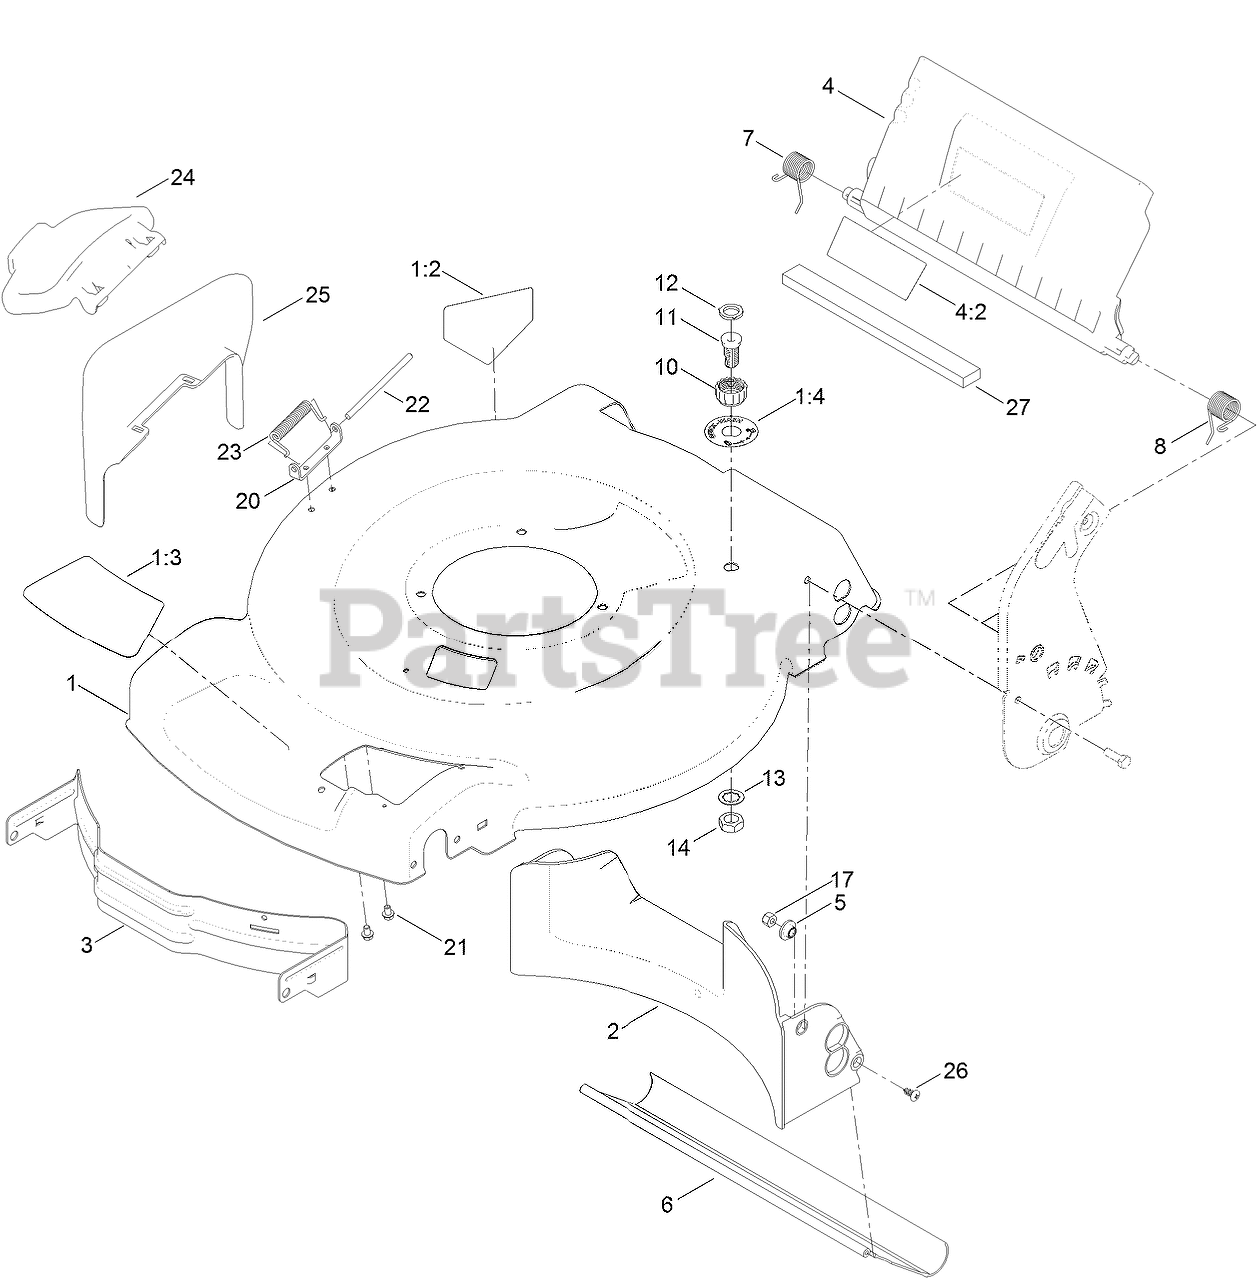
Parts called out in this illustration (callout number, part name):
1	HOUSING ASM
1:2	DECAL-DANGER
1:3	DECAL-DECK, RECYCLER
1:4	DECAL-PORT, WASHOUT
2	BAFFLE-REAR
3	BAFFLE-FRONT
4	REAR DEFLECTOR ASM
4:2	DECAL-WARNING
5	WASHER-STEPPED, BAFFLE
6	SHIELD-TRAILING
7	SPRING-TORSION
8	SPRING-TORSION
10	COUPLING-HOSE, WASHOUT PORT
11	PORT-WASHOUT
12	WASHER-SEAL, WASHOUT PORT
13	WASHER-TOOTH, INTERNAL
14	NUT-JAM
17	NUT-LOCK, NI
20	BRACKET-COVER
21	SCREW-HWH
22	ROD-COVER
23	SPRING-TORSION
24	DEFLECTOR-SIDE
25	CHUTE-DISCHARGE, SIDE
26	SCREW-PTH
27	FOAM-SEAL
